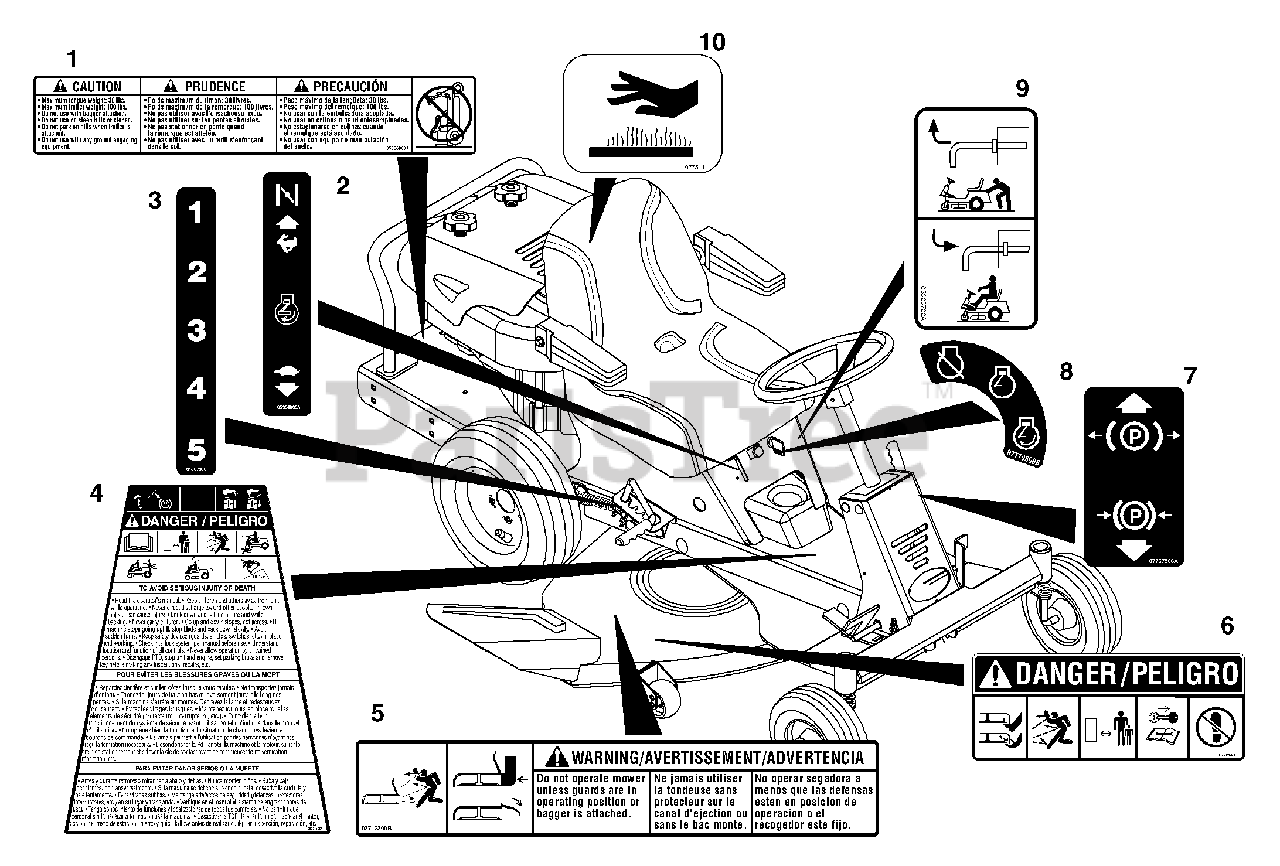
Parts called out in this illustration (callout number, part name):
1	Decal, Trailer Hitch
2	Decal, Throttle
3	Decal, 5 Position Cut Height
4	Decal, Rear Engine Rider Warning
5	Decal, Warning
6	Decal, Mower Pan Danger
7	Decal, Parking Brake Lever
8	Decal, Ignition
9	Decal, Transmission Disconnect
10	Decal, Hot Surface
